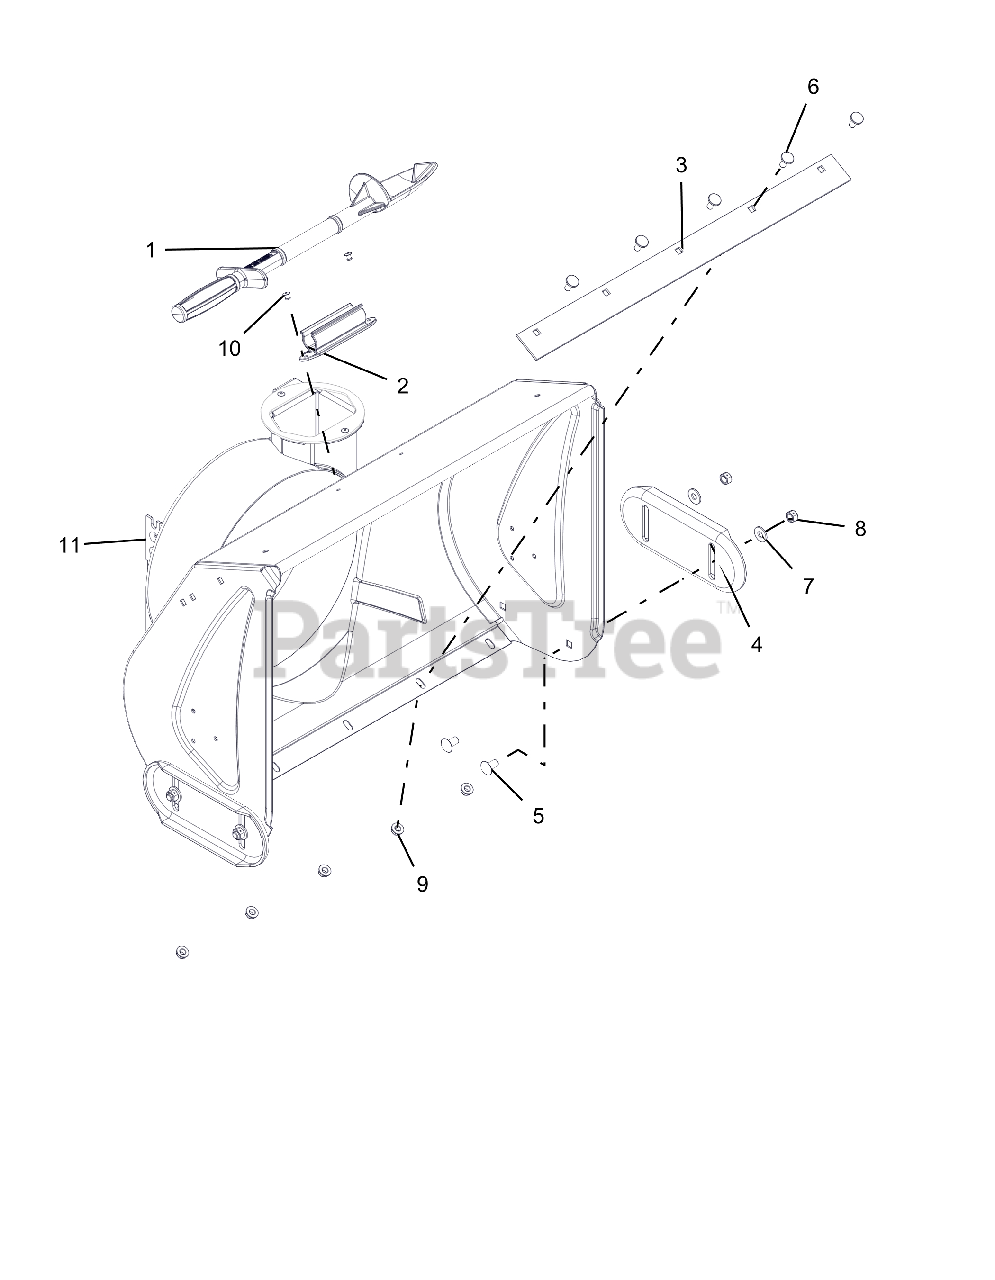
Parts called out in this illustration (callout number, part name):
1	DEVICE, SNOW CLEAN OUT
2	MOUNT, SNOW CLEAN OUT
3	SCRAPER BLADE, 24" COMPACT HI
4	SKID SHOE, REVERSIBLE
5	@BLT-RHDSSQNK .38-16X.75 G5YZ
6	BOLT, MODIFIED HEAD CARRIAGE
7	@WSHR-FL-STL.38X.875X.083 YWZC
8	@NUT-LK-CTR .38-16 YWZC
9	@NUT-LK-TOP-FLG .31-18 YWZC
10	RVT-POP .187 YZ
11	BLOWER HOUSING, 24"
